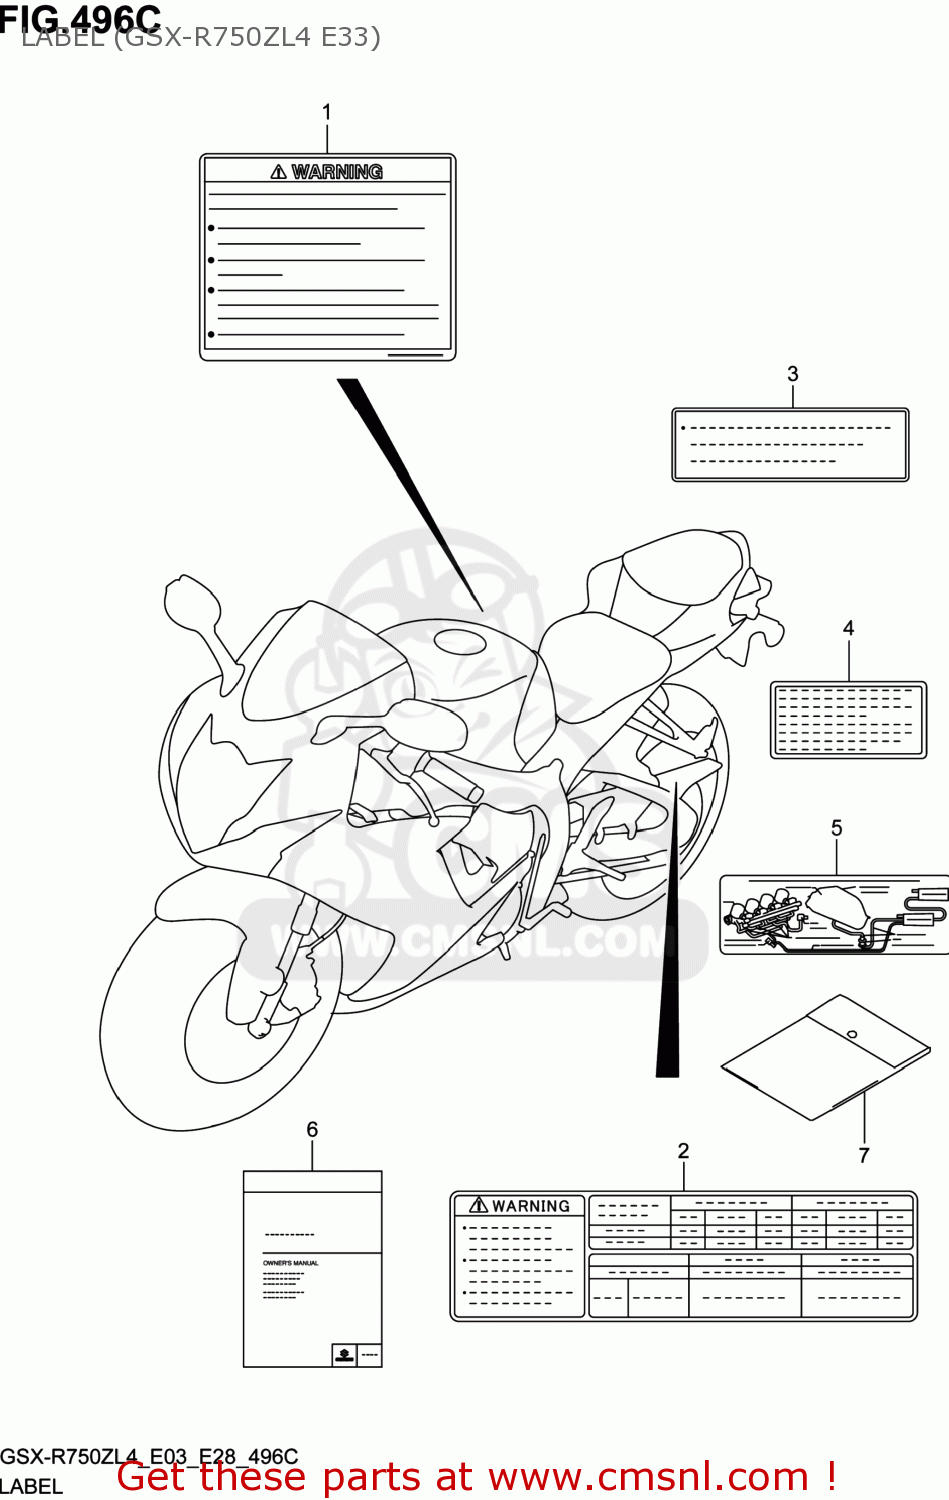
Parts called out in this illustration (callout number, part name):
1	LABEL,GENERAL WARNING
2	LABEL,TIRE INFORMATION
3	LABEL,FUEL INFORMATION
4	LABEL,MANUAL NOTICE
5	LABEL,VACUUM HOSE ROUTING
6	MANUAL,OWNER'S
7	BAG,OWNER'S MANUAL
